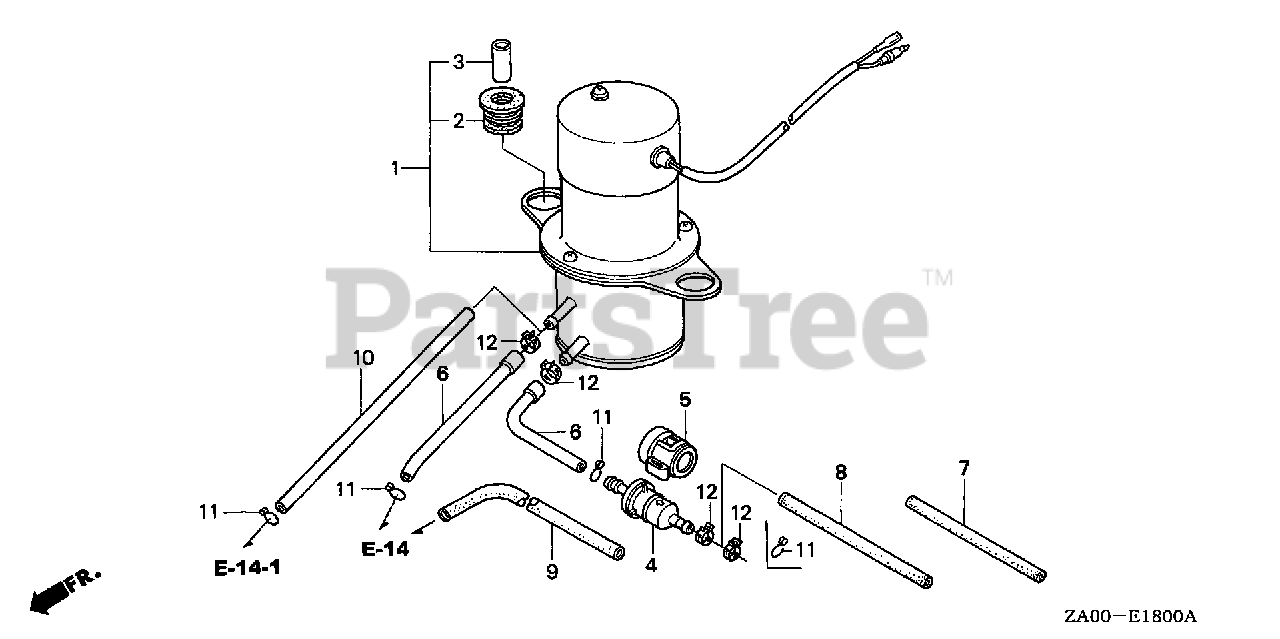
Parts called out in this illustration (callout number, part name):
4	FILTER, FUEL
9	BULK HOSE, FUEL (4.5X1000) (4.5X130)
11	CLIP, TUBE (B8)
12	CLIP, TUBE (D8.5)
